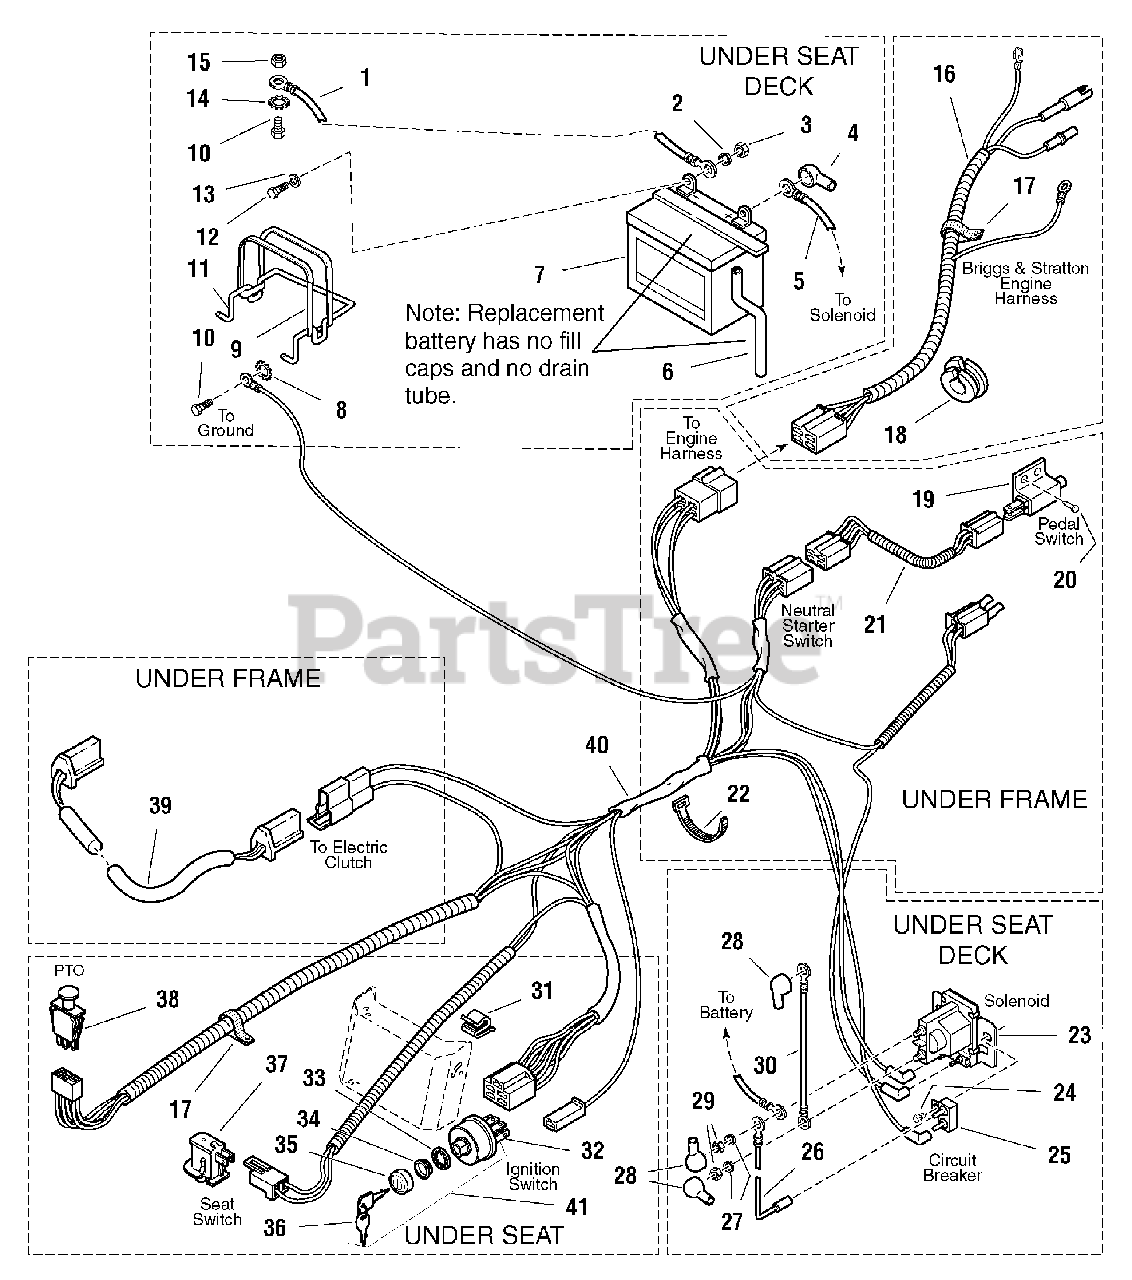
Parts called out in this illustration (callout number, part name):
1	CABLE, Battery to Ground
2	WASHER, Lock, 1/4
3	NUT, Hex 1/4-20
4	BOOT, Insulator
5	CABLE, Battery to Solenoid (Kohler Models)
5	CABLE, Battery to Solenoid (Briggs & Stratton Models)
6	TUBE, Vent (Early Models Only)
8	WASHER, Lock, External Tooth, 5/16
9	STRAP, Battery
10	CAPSCREW, Metric, M08-1.25 x 20 mm
11	BRACE, Battery
12	CAPSCREW, Hex Head, 1/4-20 x 3/4
13	WASHER
14	WASHER, Lock, External Tooth, 3/8
15	NUT, Hex, 3/8-16
16	WIRE ASSEMBLY, Harness to Engine (Briggs & Stratton Only)
17	CLAMP, Wire (11 HP B&S 5-Speed Only)
18	GROMMET (11 HP 5-Speed Models Only)
19	SWITCH, Neutral Start
21	WIRE ASSEMBLY, Neutral Switch (11 HP Coronet Only)
22	TIE, Self-Locking
23	SOLENOID
24	CAPSCREW, Hex Head, Taptite, 1/4-20 x 1/2
25	CIRCUIT BREAKER
26	WIRE ASSEMBLY
27	LOCKWASHER, 5/16
28	COVER, Terminal
29	NUT, Hex, 5/16-24
30	CABLE, Solenoid to Starter
31	CLIP (14 HP Hydro Qty=1)
32	SWITCH, Ignition (6 pole)
33	WASHER, Internal Tooth, 5/8
34	NUT
35	COVER, Keyswitch
36	KEYS (Set of 2 Keys)
37	SWITCH, Seat
38	* SWITCH, PTO, Electric Clutch
39	WIRE ASSEMBLY, Clutch
40	HARNESS, Wiring
41	IGNITION KEY SWITCH ASSEMBLY
